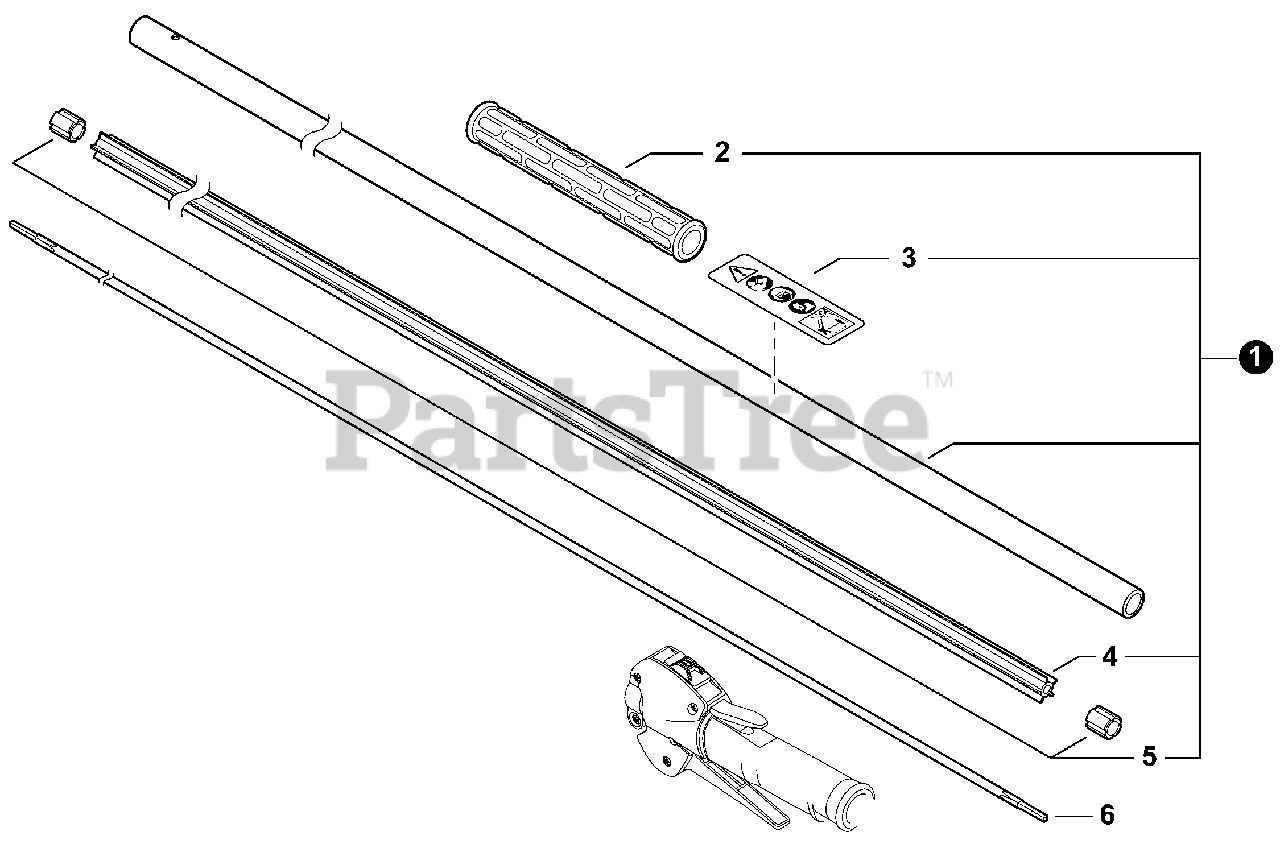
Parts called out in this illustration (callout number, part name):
1	MAIN PIPE ASSY
2	GRIP, FRONT
3	LABEL, CAUTION
6	DRIVESHAFT - FLEXIBLE
